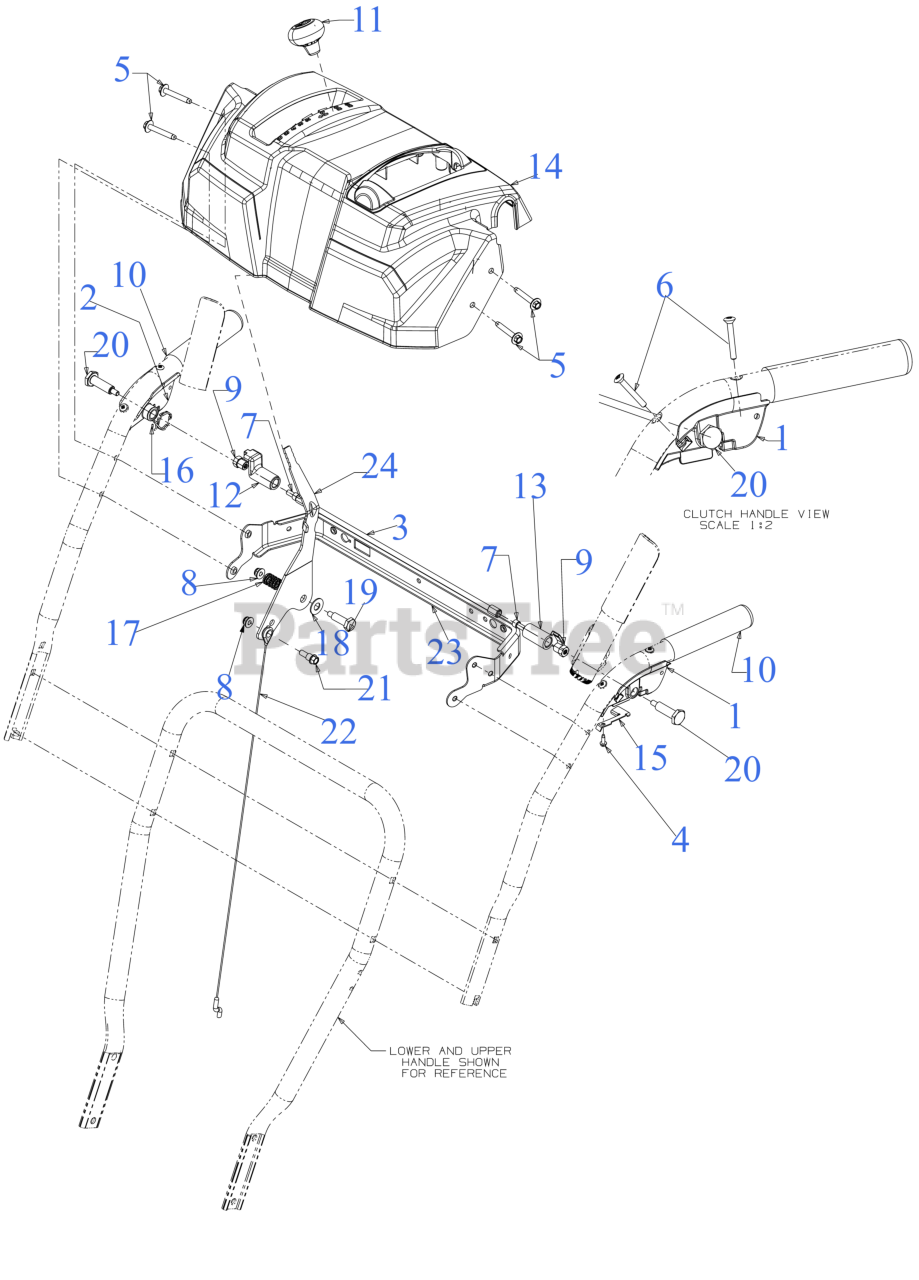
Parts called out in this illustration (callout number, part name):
1	CLUTCH LOCK HANDLE ASSEMBLY (LH)
2	CLUTCH LOCK HANDLE ASSEMBLY (RH)
4	SCREW #8-16 x .50
5	SCREW 1/4-20 x 1.625
6	SCREW #10-24 x 1.375
7	SCREW 1/4-20 x .50
8	FLANGE LOCK NUT
9	HEX NUT W/PATCH
11	SHIFT KNOB
13	CLUTCH LOCK CAM
14	HANDLE PANEL (W/O LIGHT)
15	CLUTCH SPRING
16	TORSION SPRING
17	COMPRESSION SPRING
18	FLAT WASHER .38X.88
19	SHOULDER SCREW
20	SHOULDER SCREW .437 x 1.345 1/4-20
21	SHOULDER SCREW .342X.335X1/4-20
22	SELECTION CABLE
